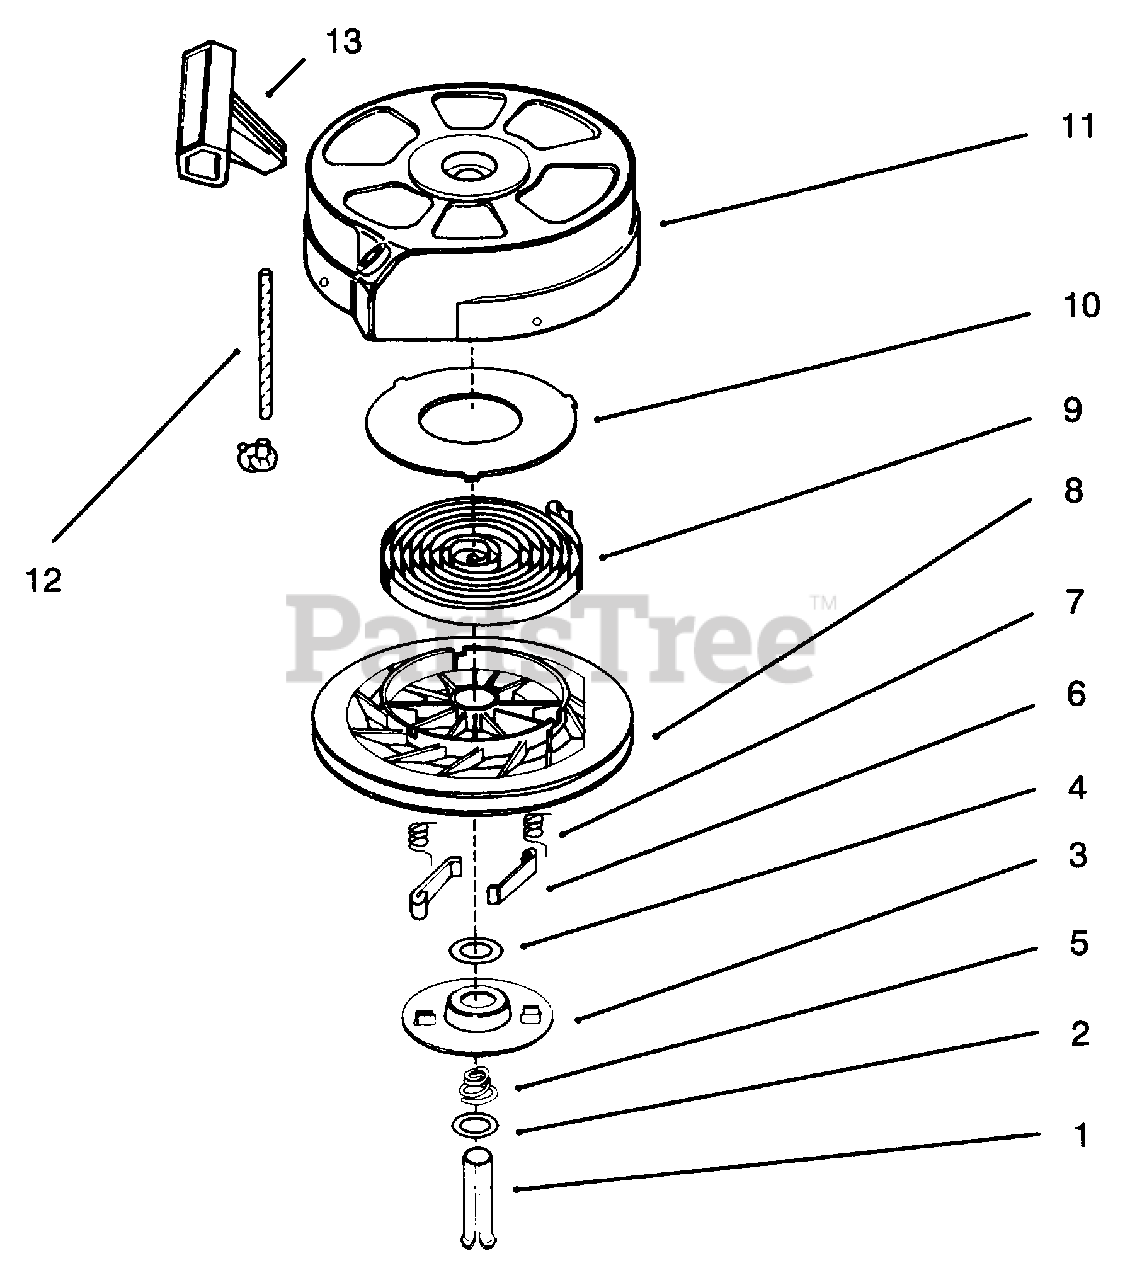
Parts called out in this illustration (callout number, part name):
1	Spring Pin (Incl. 4)
3	Retainer
5	Brake Spring
6	Starter Dog
7	Dog Spring
8	Pulley Ass'y (Incl. 9 & 10)
9	Rewind Spring
10	Spring Cover
11	Starter Housing Ass'y (40 degree grommet)
12	Starter Rope (Length 98" x 9/64" dia.)
13	Starter Handle
